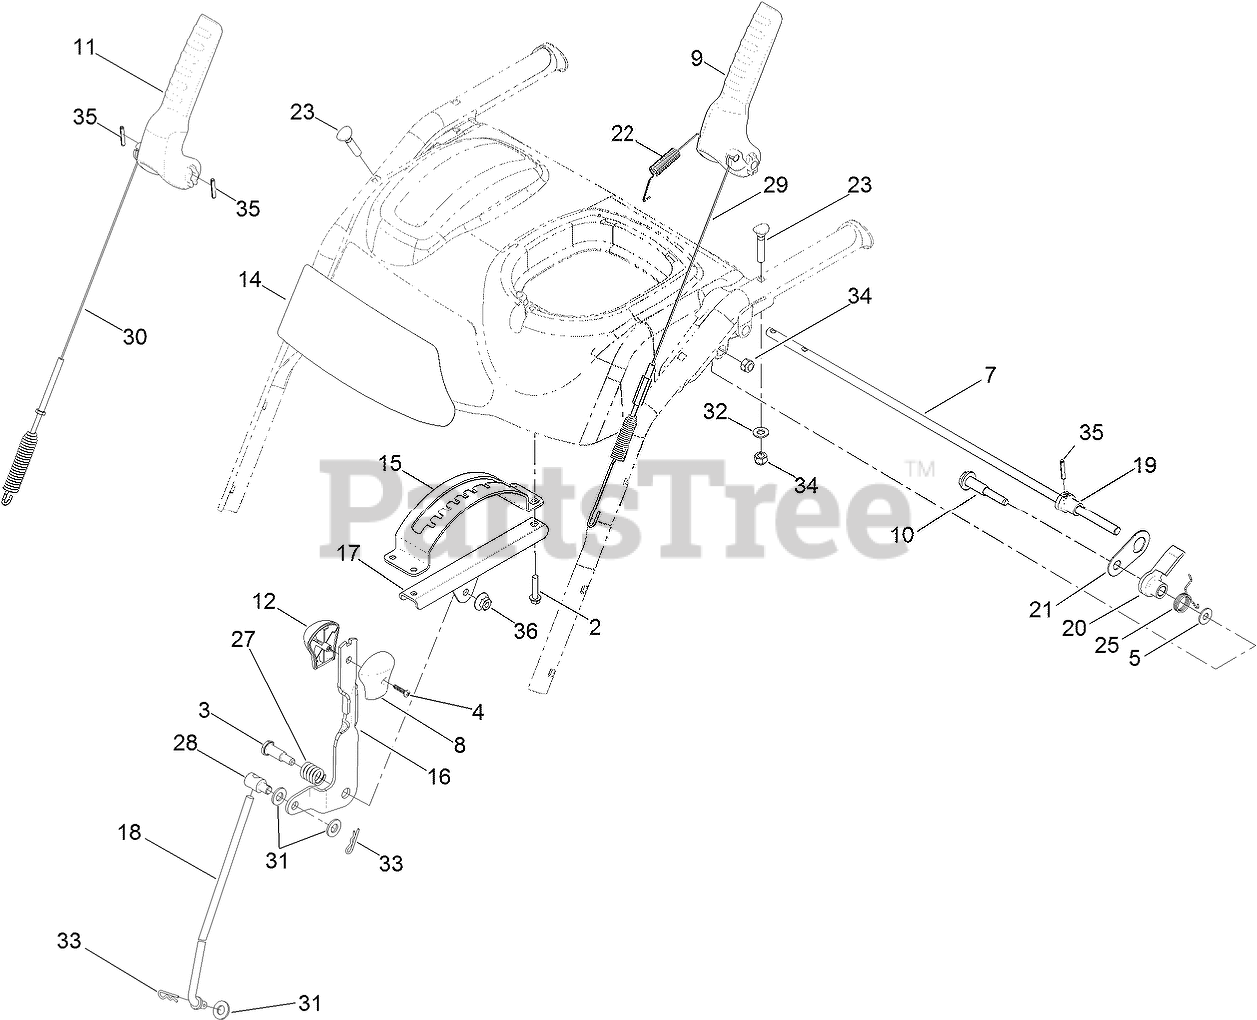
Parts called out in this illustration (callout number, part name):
2	SCREW-PLASTITE
3	SCREW-SHOULDER
4	SCREW-PPH
5	WASHER-FLAT
7	ROD-LOCKOUT
8	KNOB-SHIFT, LH
9	LEVER-TRACTION
10	SCREW-SHOULDER
11	LEVER-AUGER
12	KNOB-SHIFT, RH
14	DECAL-CONTROL PANEL
15	GUIDE-SELECTOR, SPEED
16	SELECTOR-SPEED
17	MOUNT-SELECTOR, SPEED
18	ROD-SHIFT
19	CAM-LOCKOUT
20	LATCH-LOCKOUT
21	LINK-LOCKOUT
22	SPRING-TENSION
23	SCREW-HANDLE
25	SPRING-TORSION
27	SPRING-COMPRESSION
28	TRUNNION-ROD
29	CABLE-TRACTION
30	CABLE-AUGER
31	WASHER-FLAT
32	WASHER-FLAT
33	PIN-COTTER
34	NUT-LOCK, NI
35	PIN-SPRING
36	NUT-HF
